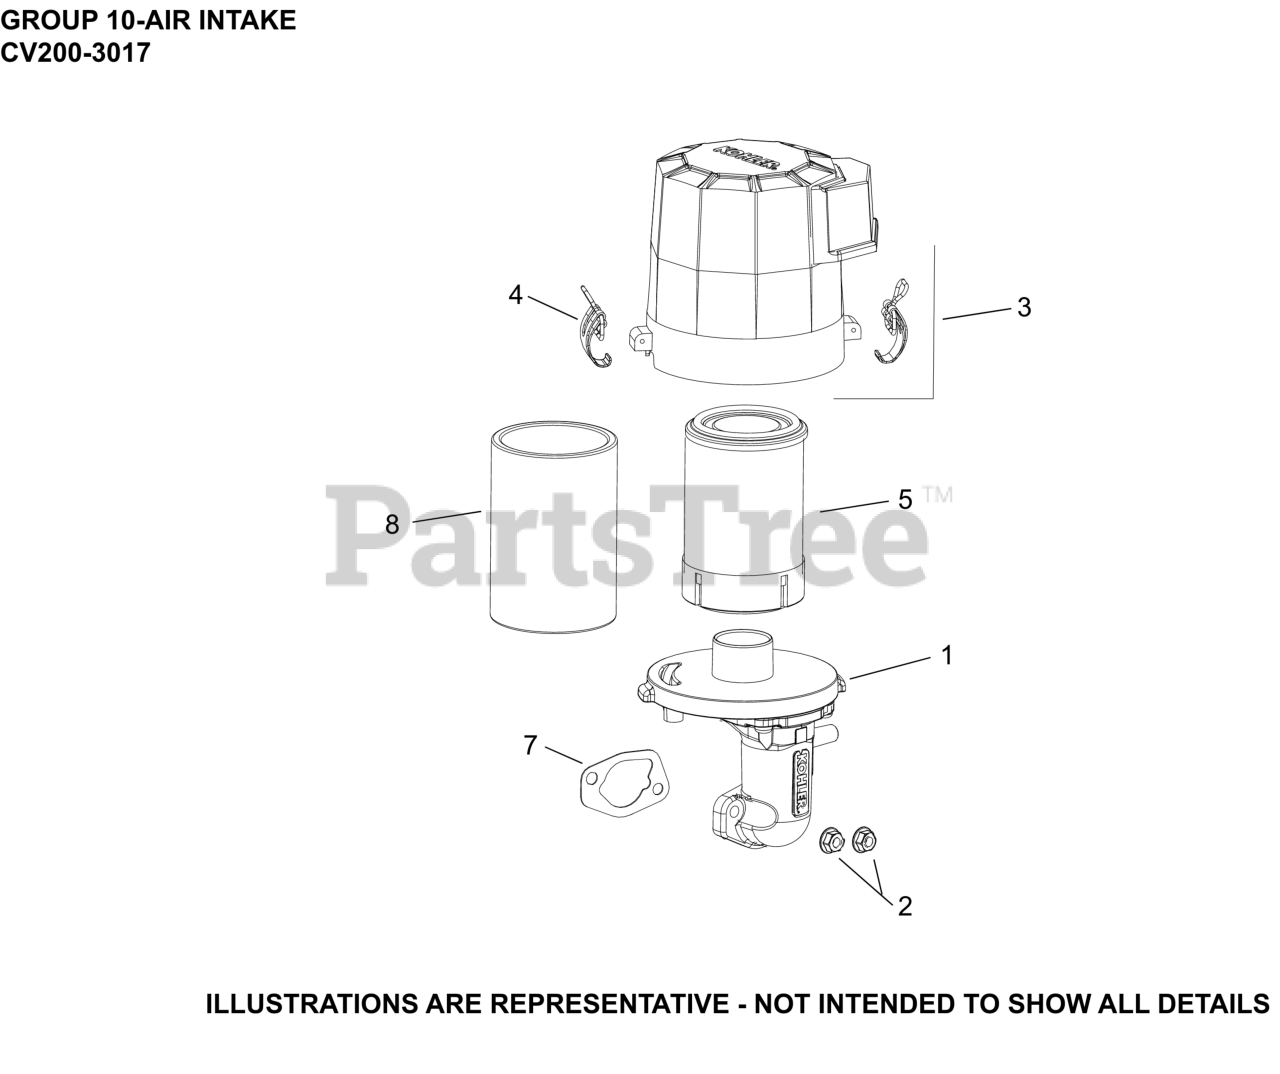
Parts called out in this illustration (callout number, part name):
1	BASE, AIR CLEANER CYCLONIC ASSEMBLY
2	NUT, HEX FLANGE LOCK (M6)
3	COVER, AIR CLEANER ASSEMBLY
4	KIT, LATCH CLIP
5	ELEMENT, AIR FILTER
7	GASKET, AIR CLEANER BASE
8	ELEMENT, PRE-CLEANER - USE 17 083 12-S
